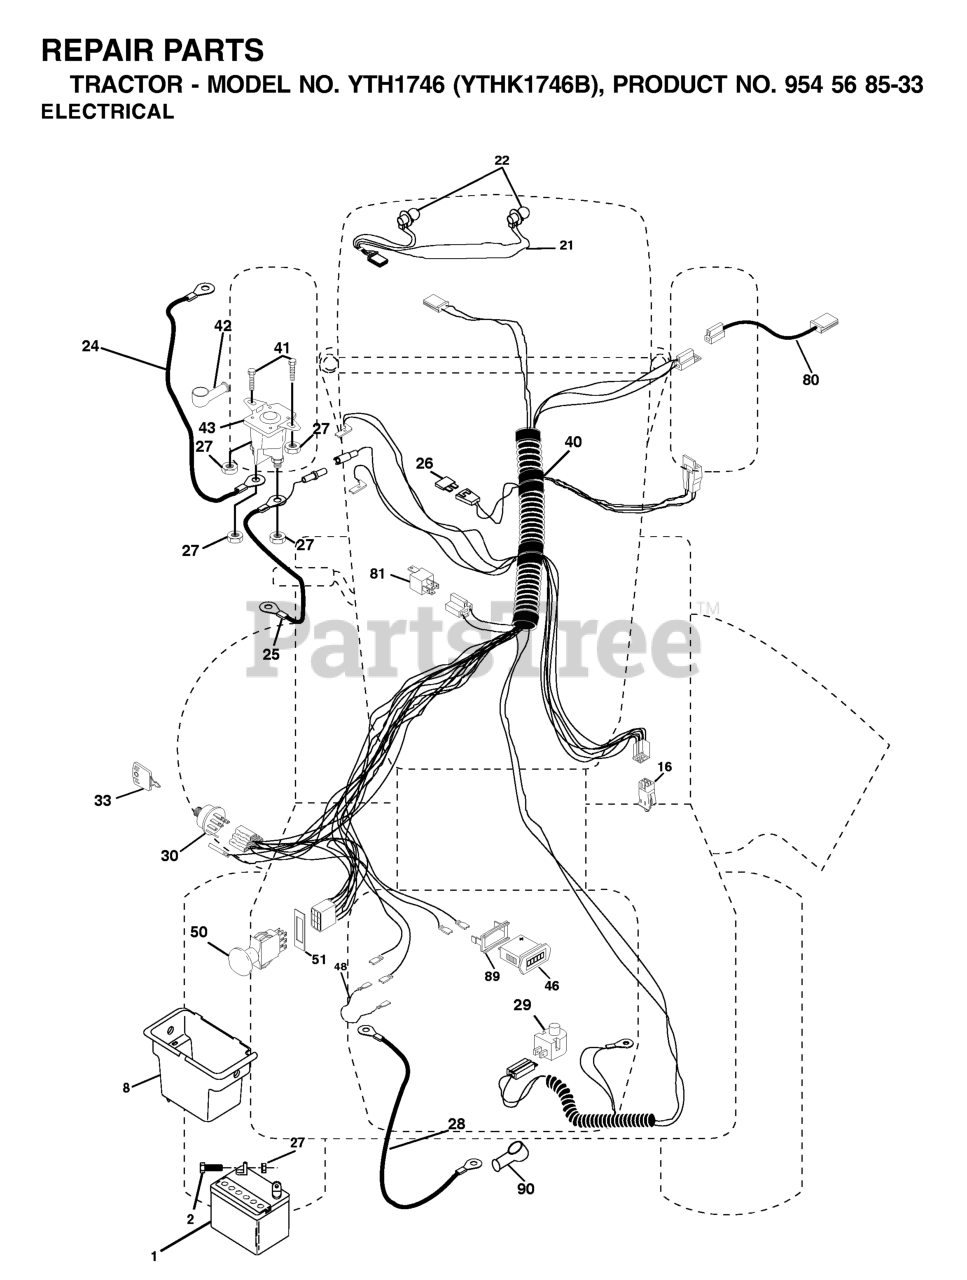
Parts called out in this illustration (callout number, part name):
1	Battery 12 Volt 25 Amp
2	BOLT.HEX.1/4.X.3/4.DICHROMATE
5	DASH.HUSQ.UPR.ELE.SVMD
8	BOX.BATTERY.FENDER
14	HOOD.PNT.HUSQVARNA.GT.
15	LENS.LH.TEX.GT.HUSQ.CL
16	SWITCH INTERLOOK PUSH-IN
18	GRILLE.ASM.TX.GT.HUSQ
21	HARNESS.ASM.LIGHT WSL
24	BATTERY CABLE GT
25	LENS.RH.TEX.GT.HUSQ.CL
25	CABLE BATTERY
26	FUSE 20AMP
27	NUT
28	CABLE T
29	PLUNGER SWITCH (COLOR:OLIVE)
30	IGNITION SWITCH
33	KEY MLD GEN DELTA
34	PLATE.ENGINE.WELDED.CHASSIS
36	SCREW 5/16"
37	FENDER.PNT.TX.GT.CH/FW.ORANGE
40	HARNESS IGN.
41	BOLT
42	TERMINAL COVER
43	SOLENOID
46	HOUR METER
48	ADAPTER.AMMETER
50	RP.PTO.SWITCH.8 TERMINAL.BLACK
51	FRAME RETAINING RING
52	LOCKNUT
58	BRKT.SUPPORT.FNDR/TANK
68	Screw 5/16-18 x 1/2 Hex, Self Tapping 5/16-18 x 1/2
80	HARNESS, CLUTCH
81	RELAY.ASSY.T
89	BRACKET SNAP-IN HOURMETER
90	COVER TERMINAL
99	ROD.BYPASS.HYDRO.0510/0610.GT
130	SCREW
150	AIR.DUCT.TEXGT.HUSQ.31
152	SHIELD.BROWNING.W/TEX
161	CONSOLE.FUEL.WINDOW.HU
162	SCREW.HI-LO.CONSOLE
165	SUPPORT.TANK.REAR.W/TEX
175	PLATE.CROSSMEMBER.HUSQ
176	SCREW.#10-24X5/8.RN.QU
177	BUSHING, STEERING
178	CARGO.ASM.NET.TXGT.W/C
180	CHASSIS.WLDMT.TX.GT.05
181	BUSHING.MNT.FEND.CRGO.
182	DASH.LOWER.COMMON.12V.
183	BOLT.5/16-18X1-1/4 FULL.THREAD
189	SCREW
194	NUT LOCK HEX FLANGE 5/16-18
195	PLUG.HOLE.DASH.LOWER.12V.BLK
196	RP CONSOLE.ASM.DECKLFT.W/
199	PLATE.DECK.LIFT.HUSQVARNA.GT
202	VENT.SIDE.HOOD.HUSQ.RH.GREY
203	VENT.SIDE.HOOD.HUSQ.LH.GRAY
204	VENT.TOP.HOOD.HUSQVARN
205	SKIRT.HOOD.SIDE.HUSQ.RH.GREY
206	SKIRT.HOOD.SIDE.HUSQ.LH.GREY
207	BEZEL.RH.TEX.GT.HUSQ
208	BEZEL.LH.TEX.GT.HUSQ
209	INSERT.HEX.GRILL.HUSQ.GREY
210	INSERT.HEX.GRILL.HUSQ.
211	INSERT.HEX.GRILL.HUSQ.
212	INSERT.HEX.GRILL.HUSQ.
213	BOLT
214	CLIP.RETAINER.TINNER.
217	ROD PIVOT CHASSIS/HOOD
218	X-PIECE.HOOD.STOP.NON/
221	REFLECTOR.LH.TEX GT HU
228	STUD.FASTNER.W/ANTI-ROTATE
235	SPACER FENDER
236	NUT.CENTERLOCK.5/16-
237	PLUG.MOUNT.CARGO.BLK
